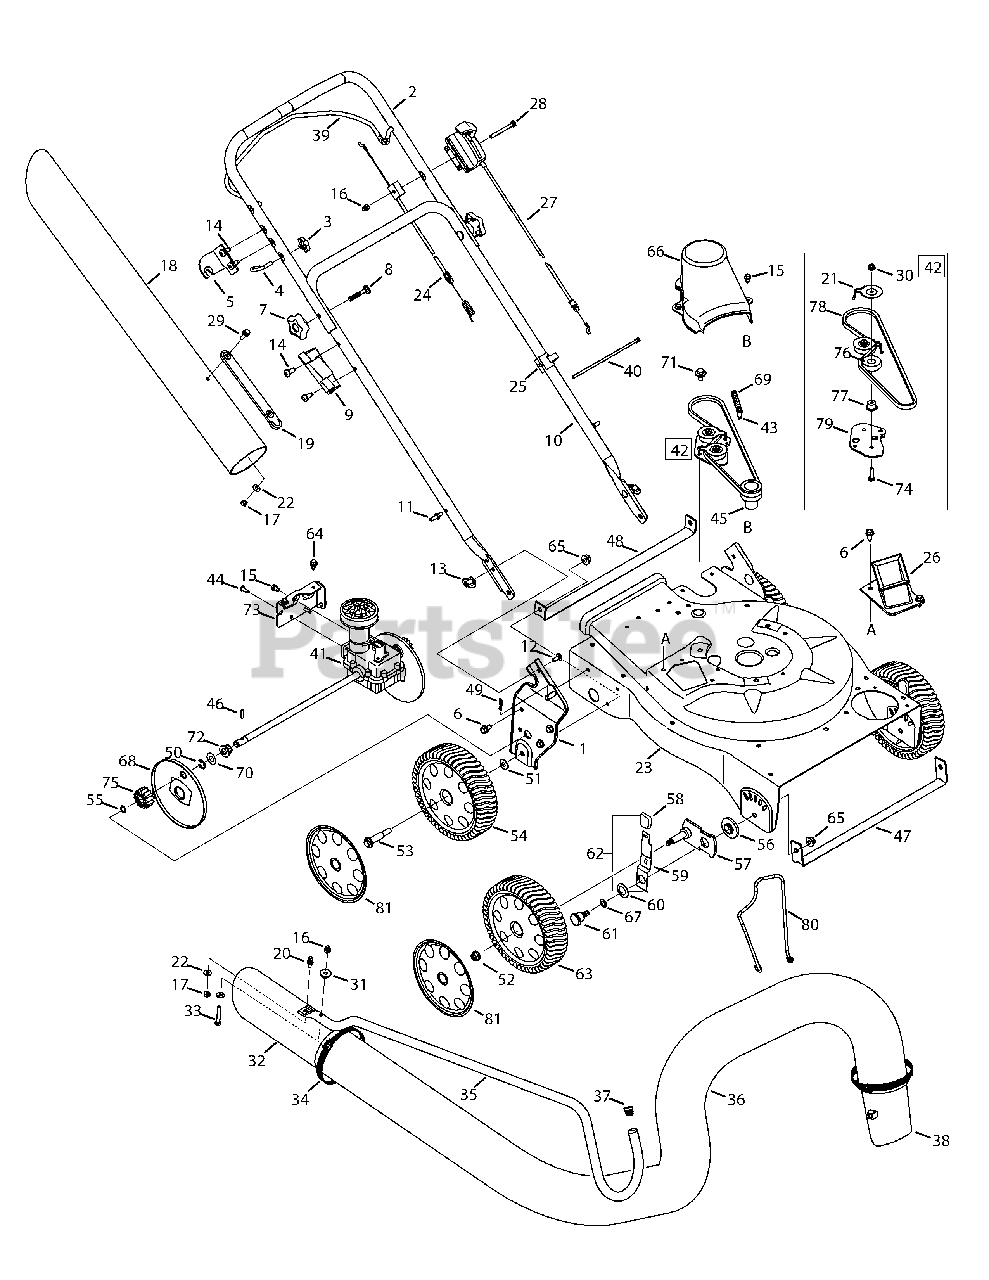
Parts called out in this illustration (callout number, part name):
1	Handle Bracket Ass’y RH
2	Upper Handle
5	Upper Handle Bracket
6	Hex Cap Screw, 5/16-12 x.750
7	Handle Knob, 5/16-18
8	Carriage Bolt
9	Nozzle Handle Clip
12	Carriage Screw, 1/4-20 x.75
13	Wing Nut, 1/4-20
14	TT Screw, 5/16-18 x .750
15	Screw, 1/4-20 x .500
16	Cap Lock Nut, 1/4-20
17	Hex Lock Nut, 1/4-20
18	Hose Extension
19	Chute Strap
21	Belt Keeper
22	Flat Washer.271 ID x.630 OD
23	Upper Flail Housing
24	Drive Control Cable
25	Cable Guide
26	Chipper Chute Assembly
27	Speed Control Cable
28	Hex Screw, 1/4-20 x 2.50
29	Screw, 1/4-20 x .75
30	Flange Lock Nut, 1/4-20
32	Hose Nozzle
33	Hex Cap Screw, 1/4-20 x 2.625
34	Adjustment Clamp
36	Vacuum Hose
37	Handle Plug
38	Hose Adapter
39	Drive Control
40	Cable Tie
41	Transmission Assembly
42	Idler Assembly
43	Shoulder Screw, #12-24 x .30 x .46
44	Screw, #12-16 x .750
45	Impeller Hub
46	Dowel Pin
47	Front Wheel Support Brace
48	Rear Wheel Support Brace
49	Cotter Pin
51	Flat Washer, .406 x .875 x .105
52	Flange Lock Nut, 3/8-16
53	Shoulder Screw, 3/8-16
54	Wheel, 8 x 2
55	Snap Ring
56	Height Adjustment Bearing
57	Pivot Arm Assembly
58	Height Adjustment Knob
59	Spring Lever
60	Bell Washer, .760 ID x.25 OD
61	Shoulder Screw, .750 x.500
62	Height Lever Assembly
63	Wheel 8 x 2
64	Screw, 1/4-20 x .625
65	Flange Lock Nut, 3/8-16
66	Belt Cover
67	Thrust Washer, .375 ID x.70 OD
68	Wheel Cover
69	Extension Spring, .375 x 2.95
70	Flat Wash, .508ID x1.00OD x.020
71	Shoulder Screw, .560 x.165
72	Drive Axle Bushing
73	Transmission Mounting Bracket
74	Screw, 1/4-20 x 1.00
75	Spur Gear - RH
76	Ball Bearing
77	Flange Spacer,.260 x.659 x.517
78	Belt, 3/8 x 32.5
79	Idler Bracket
80	Tube Holder
81	Hubcap, 8"
